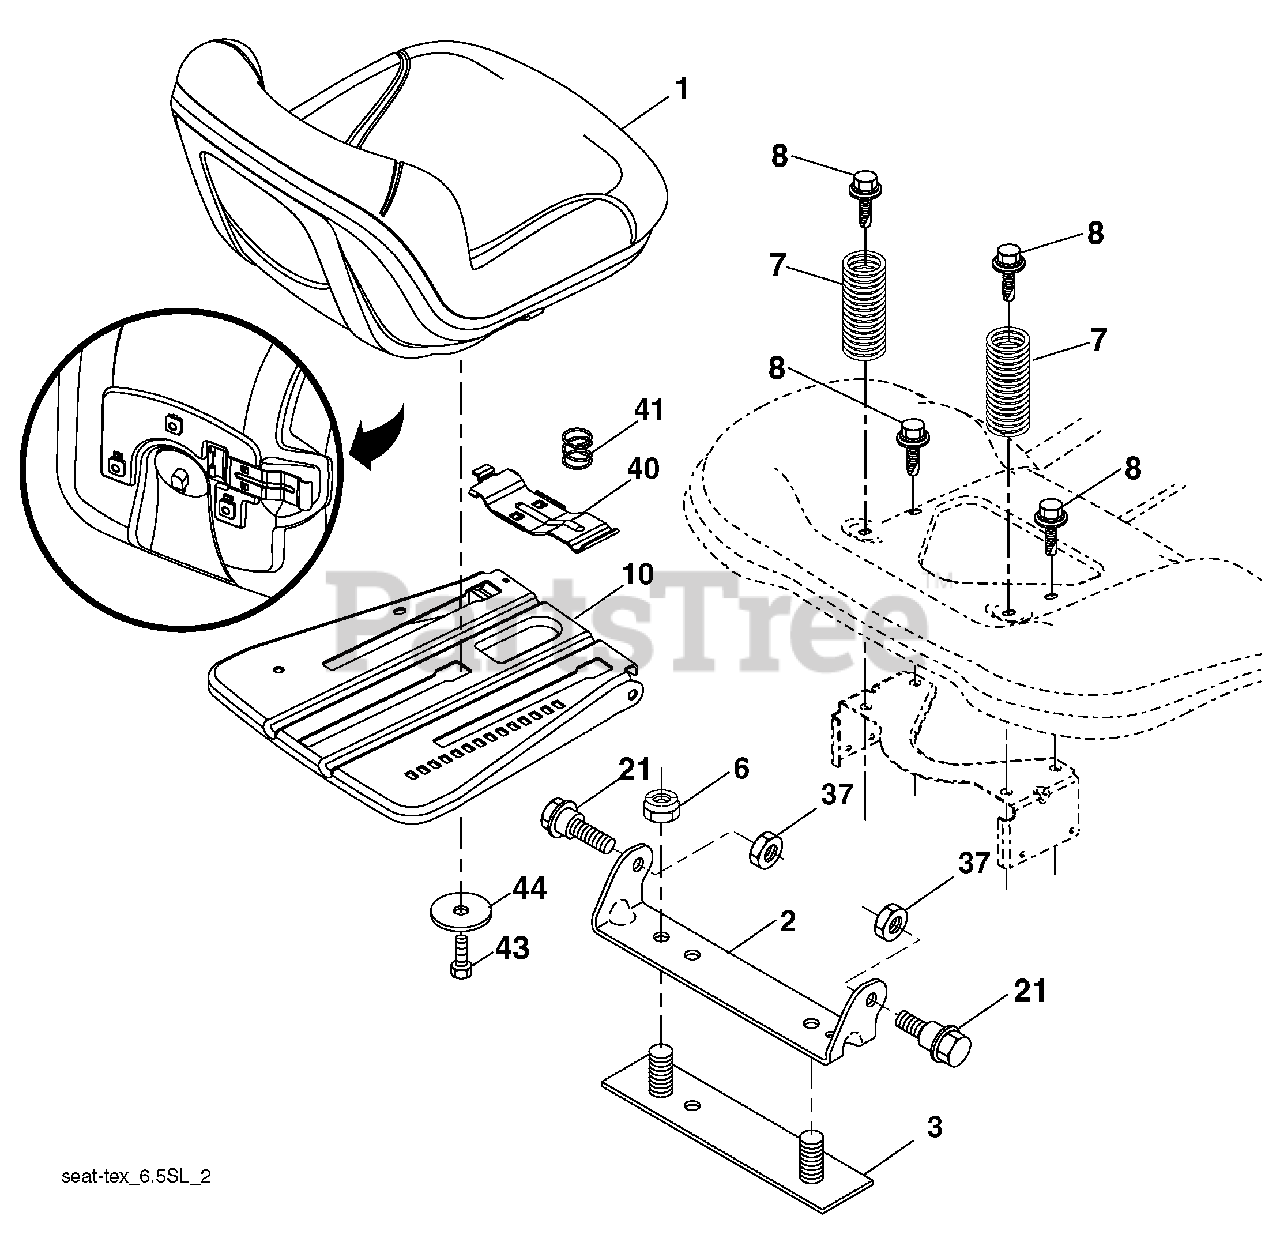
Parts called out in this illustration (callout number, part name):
1	Seat
2	Bracket Pivot Fender
3	Strap, Asm Fender
6	Nut, Lock w/Ins. 3/8-16 unc
7	Spring, Seat Cprsn
8	Bolt 5/16-18 unc x 3/4 w/Sems
10	Pan, Seat
21	Bolt, Shoulder 5/16-18
37	Nut, Lock 5/16-18 unc
40	Handle Slide
41	Spring Latch
43	Bolt 3/8-16 unc x 3/4
44	Washer 13/32 x 2 3/8 x 12 Ga.
